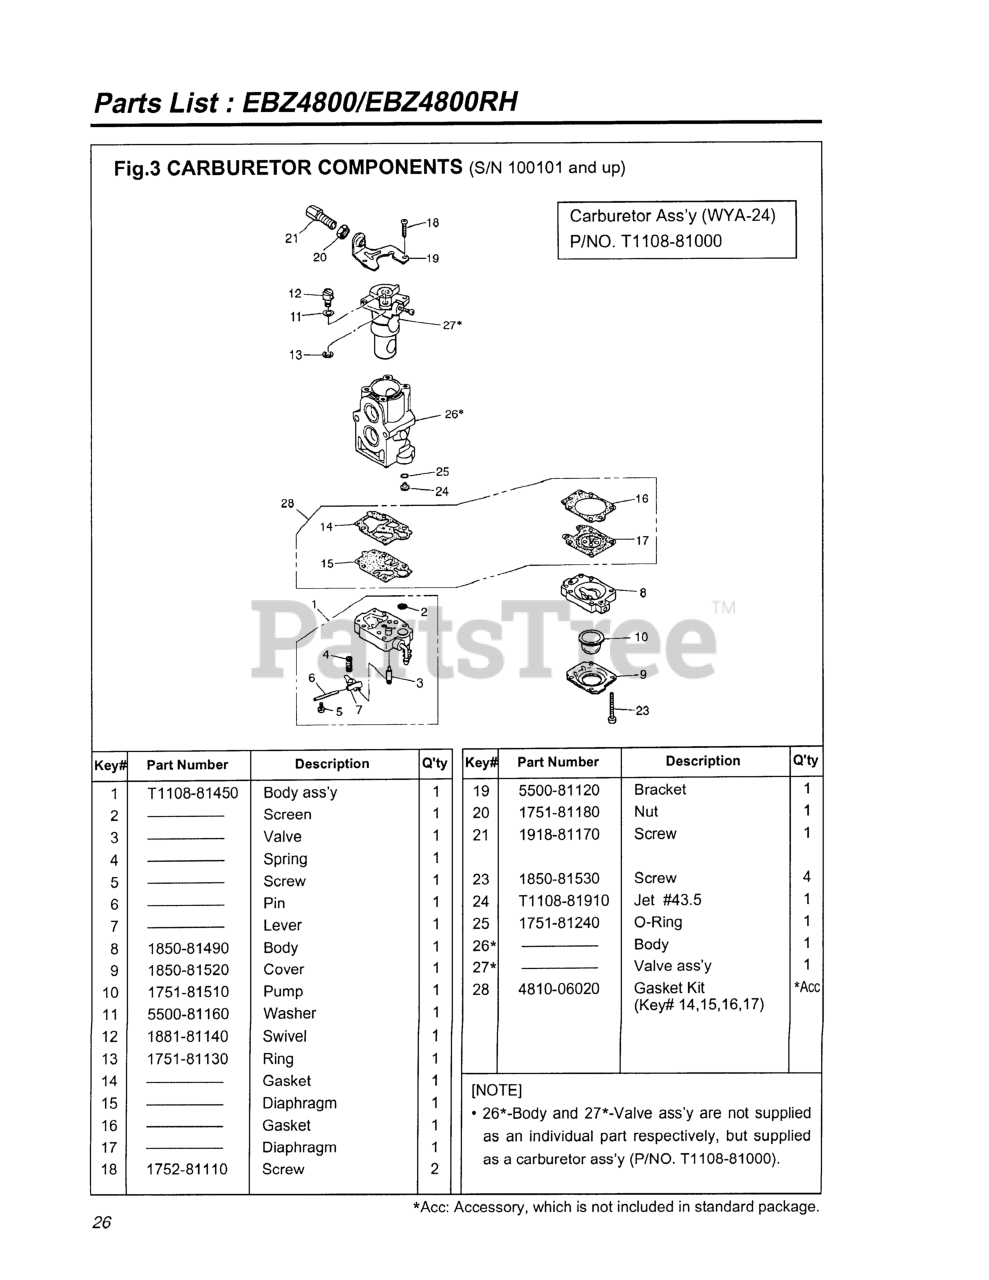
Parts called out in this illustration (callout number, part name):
1	BODY ASSY.
2	SCREEN
3	VALVE, INLET
5	SCREW
6	PIN
7	LEVER
8	BODY, PURGE
9	COVER, PUMP
10	PUMP, PRIMING
11	WASHER
12	SWIVEL
13	RING
14	GASKET
15	DIAPHRAGM
16	GASKET
17	DIAPHRAGM
18	SCREW
20	NUT, CABLE ADJUSTER
21	SCREW, CABLE ADJUSTER
23	SCREW
24	JET 43.5
25	RING, O
26	CARBURETOR (WYA 24A)
27	CARBURETOR (WYA 24A)
